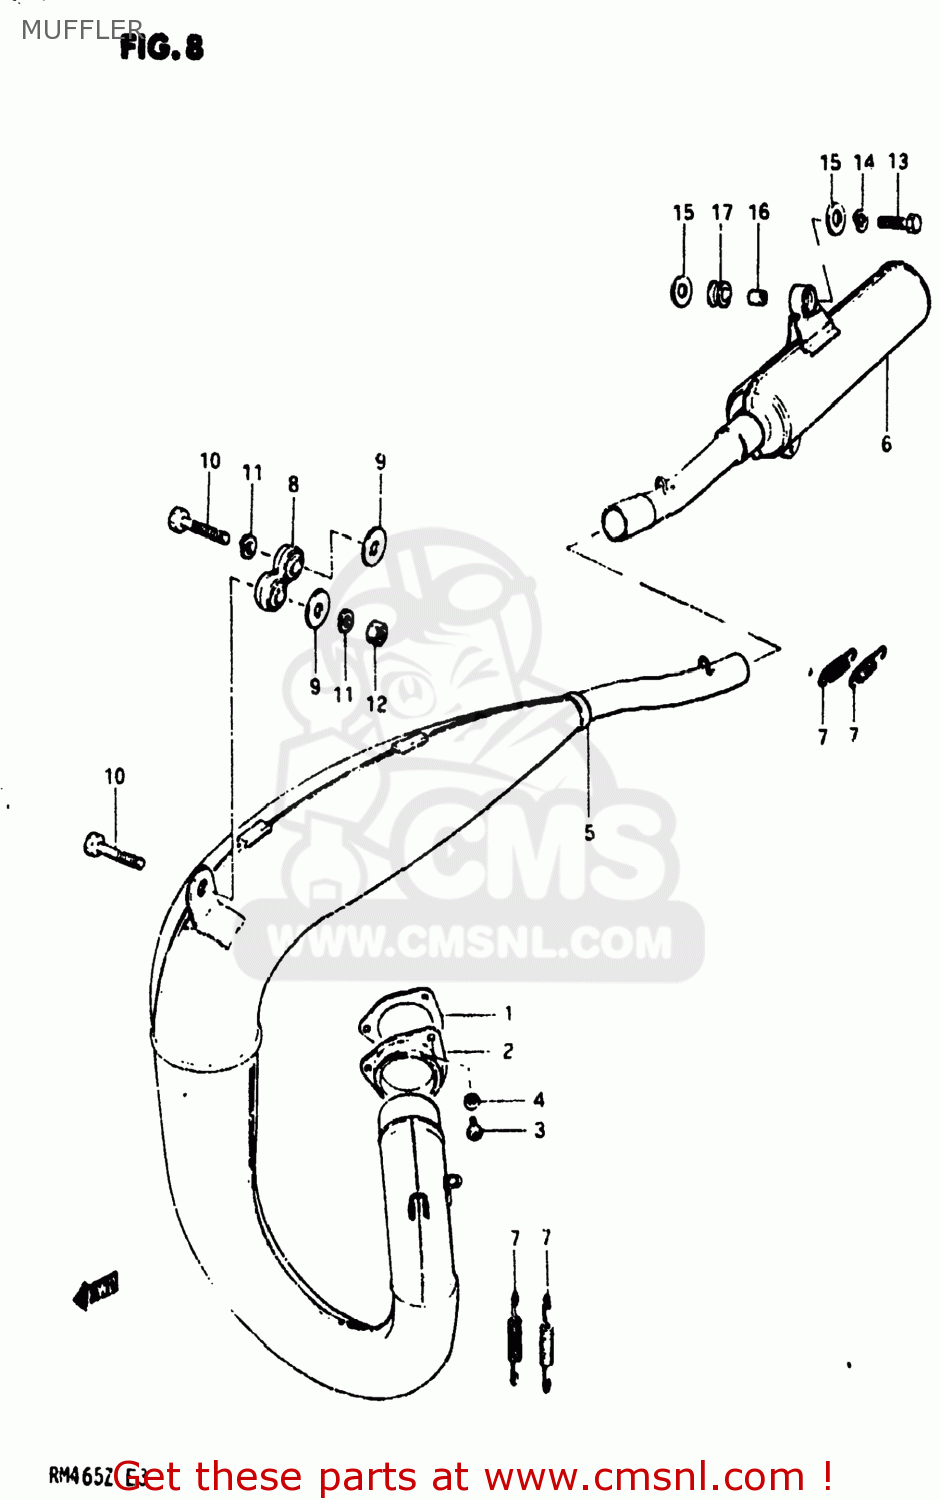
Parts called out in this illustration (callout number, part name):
1	GASKET,EXHAUST PIPE (MCA)
2	FLANGE,EXHAUST PIPE
3	SCREW
4	LOCK WASHER
5	BODY,MUFFLER
6	BODY,MUFFLER
7	SPRING
8	DAMPER,MUFFLER
9	WASHER
10	BOLT(8X32)
11	LOCK WASHER
12	NUT
13	BOLT(8X32)
14	LOCK WASHER
15	WASHER (8.5X29X1.6)
16	SPACER (8.6X12X17.5)
17	CUSHION
